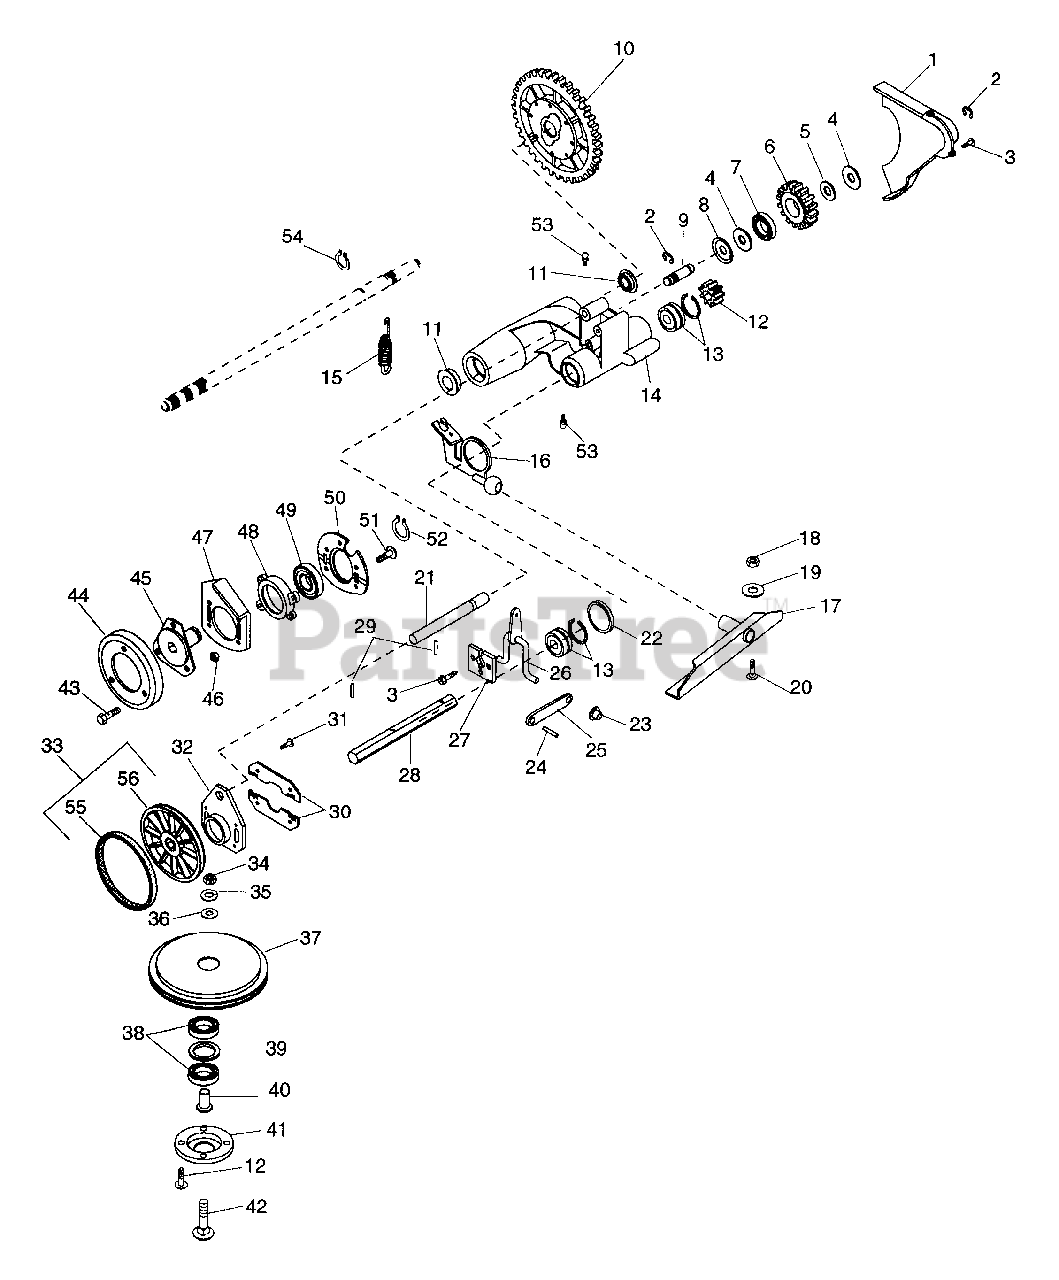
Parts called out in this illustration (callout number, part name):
1	GEAR COVER
2	RG-RTNG-EXT .438X.035
3	SCR-TAP 12-24X.50 HWH PL TR
4	WSHR-FL-STL .520X.827X.062 YZ
5	WSHR-FL-STL .505X.880X.072 PL
6	IDLER GEAR
7	BRG-BALL .500X1.38X.437
8	RETAINER
9	IDLER SHAFT
10	DIFFERENTIAL ASSEMBLY
11	BRG-BALL .625X1.383X.50
13	BRG-BALL .562X1.375X.437
14	DRIVE MOUNT
15	SG-TENS .051X.60X2.25 WLD 7.0
16	DRIVE ACTUATOR WELDMENT
17	PIVOT CHANNEL WELDMENT
18	NUT-LK .312-18 GR A PL
19	WSHR-FL-STL.344X.688X.065PL
20	BLT-RDHDSQNK .312-18X.62SHTPL
21	ROD - GUIDE
22	WSHR-FL-STL 1.390X2.00X.020 PL
23	PUSH NUT, .25
24	PIN-ROLL .125X.50
24	PIN-ROLL .125X.63
25	SHIFT LINK
26	SHIFT ARM WELDMENT
27	RETAINER PLATE
28	HEX SHAFT
29	PIN-ROLL .188X.88
30	THRUST PLATE
31	SCR-TAP 10-24X.375 HWH PL TR
32	GUIDE PLATE
33	FRICTION WHEEL ASSEMBLY
34	NUT-HEX .312-18
35	WSHR-LK .312X.097 PL HVY
36	WSHR-FL-STL .328X.875X.062 PL
37	FRICTION SHEAVE
38	BRG-BALL .625X1.375X.44
39	WSHR-FL-STL 1.062X1.344X.032PL
40	SPINDLE - BEARING
41	RETAINER - BEARING
42	BLT-RDHDSQNK .31-18X1.75 PL
43	BLT-HEX .25-20X.50 PL GR2
44	FRICTION DISC
45	FRICTION WHEEL HUB
46	NUT-LK-CTR .250-20 PL
47	BEARING PLATE
48	BEARING RETAINER
49	BRG-BALL 1.0X2.0X.56
50	BEARING RETAINER
51	TAPTITE M5-0.8X16MM H-FL-PL
52	RG-RTNG-EXT 1.00X.042
53	FTG-LUBE .25-28X.256 YWZC
54	RG-RTNG-EXT .625X.035
55	FRICTION RING
56	FRICTION WHEEL HUB
